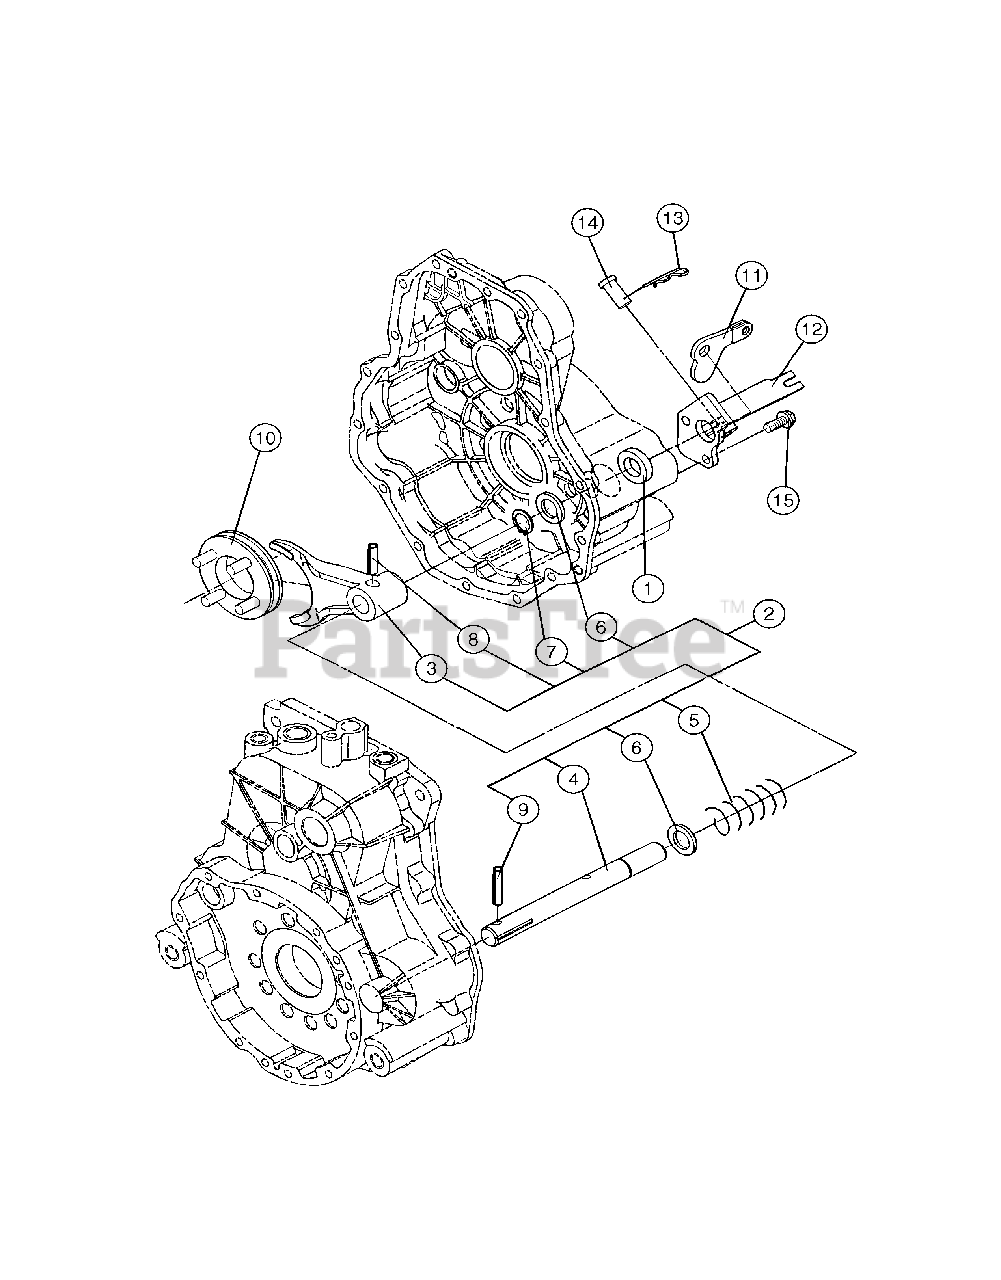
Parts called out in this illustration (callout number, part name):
1	Seal, TC4 20 35 7
2	Differential Lock Kit
3	Fork, Differential Lock
4	Shaft, Differential Lock
5	Spring, Differential Lock
6	Spacer, 20 x 32 x 3.2
8	Pin, 8.0A x 32
9	Pin, 8.0A x 40
10	Slider, Differential Lock
11	Arm, Differential Lock
12	Bracket, Differential Lock
13	Pin, 12
15	Tapping Screw, 8 x 20
15	Flange Bolt, M8 x 20
